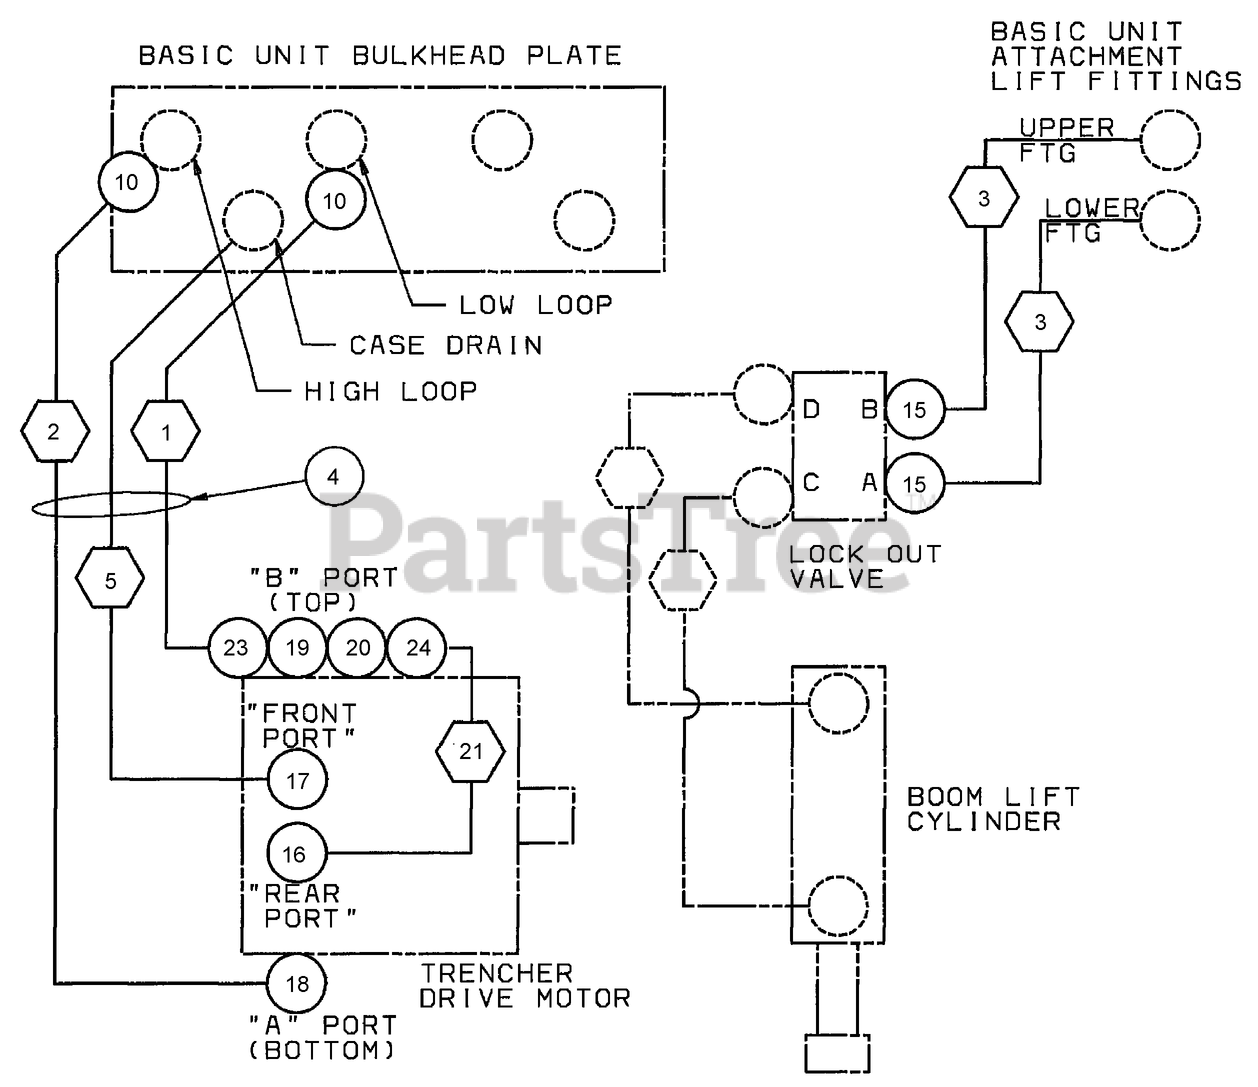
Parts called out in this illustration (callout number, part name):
1	HOSE-Low Pressure Loop
2	HOSE-High Pressure Loop
3	HOSE-Boom Lift
4	STRAP-TIE
5	HOSE-Case Drain
10	REDUCER-16FF-12MF
15	CONNECTOR
16	ELBOW-90 Deg, 1/2 to 5/8
17	CONNECTOR-Str Thd 5/8, 37FL-ORB 5/8
18	FITTING-STRAIGHT
19	ADAPTER-Tee, ORB / JIC
20	FITTING-Restrictor
21	HOSE-Trencher Motor Flush
23	ELBOW-SWIVEL, 90 DEG
24	ELBOW-90 Swivel 37FL 1/2 Tube
